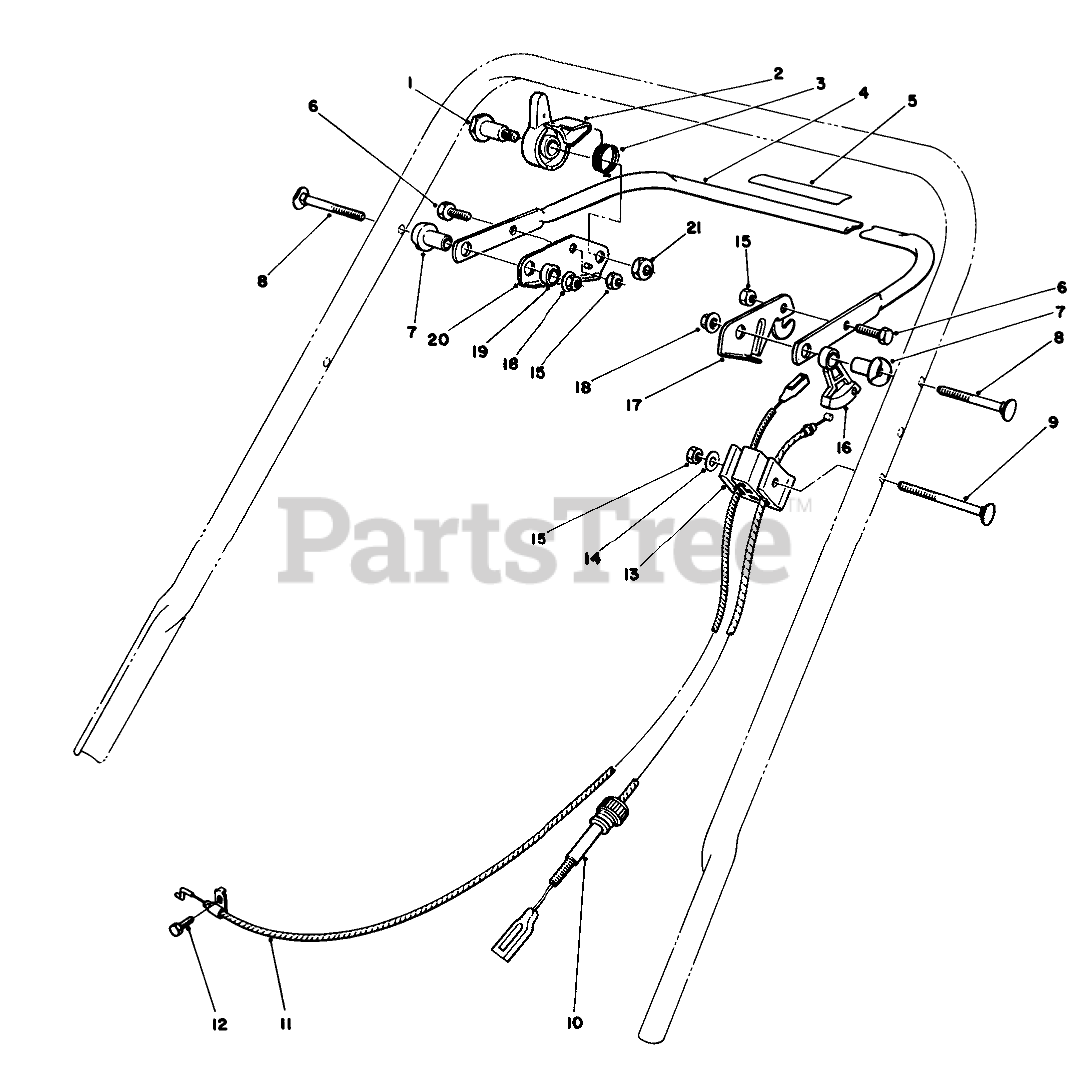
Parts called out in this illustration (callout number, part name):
1	SHOULDER BOLT
2	NEUTRAL LOCKOUT
3	TORSION SPRING
4	CONTROL BAR PROMO
5	Decal-Variable Speed
6	SCREW-HH
7	SPACER-SUPPORT
8	5/16-18 X 2 HNDLE SCREW
9	HANDLE SCREW
10	CABLE-TRACTION
11	BRAKE CABLE
12	SCREW-HH
13	SUPPORT-CABLE
14	WASHER-FLAT
15	NUT-LOCK, NI
16	LEVER-TRACTION
17	Lever-Control
18	NUT-LOCK, NI
19	SPACER-NYLON
20	Bracket-Lockout
21	NUT-LOCK, NI
